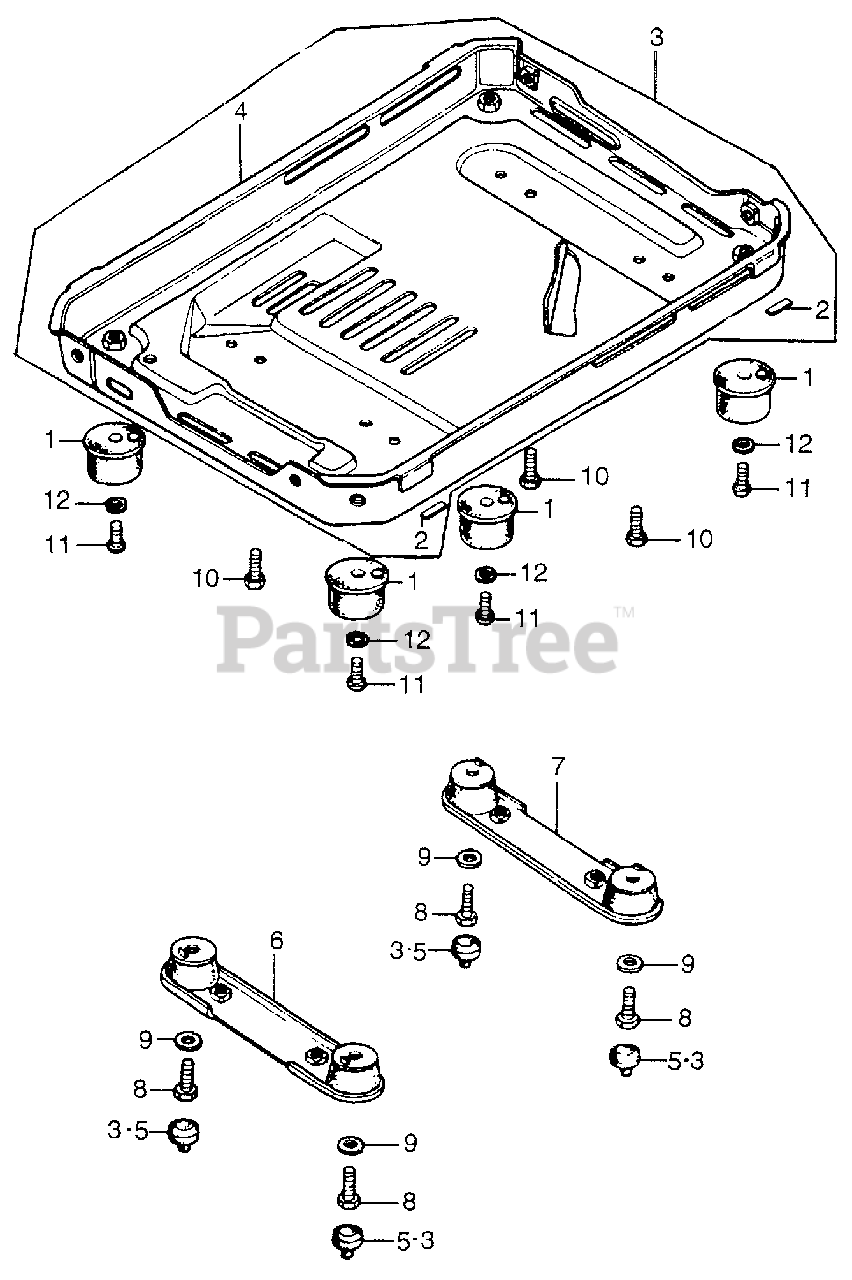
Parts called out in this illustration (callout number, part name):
1	RUBBER (LOWER)
2	RUBBER, GUIDE
3	COVER (LOWER) *NH1* (BLACK) (NOT AVAILABLE)
4	COVER (LOWER) *NH1* (BLACK)
5	RUBBER, SETTING STOPPER (NOT AVAILABLE)
6	FRAME, ENGINE
7	FRAME, ALTERNATOR (NOT AVAILABLE)
8	BOLT, HEX. (6X12)
9	WASHER (6MM)
10	BOLT, HEX. (5X10)
11	SCREW, PAN (5X10)
12	WASHER, SPRING (5MM)
